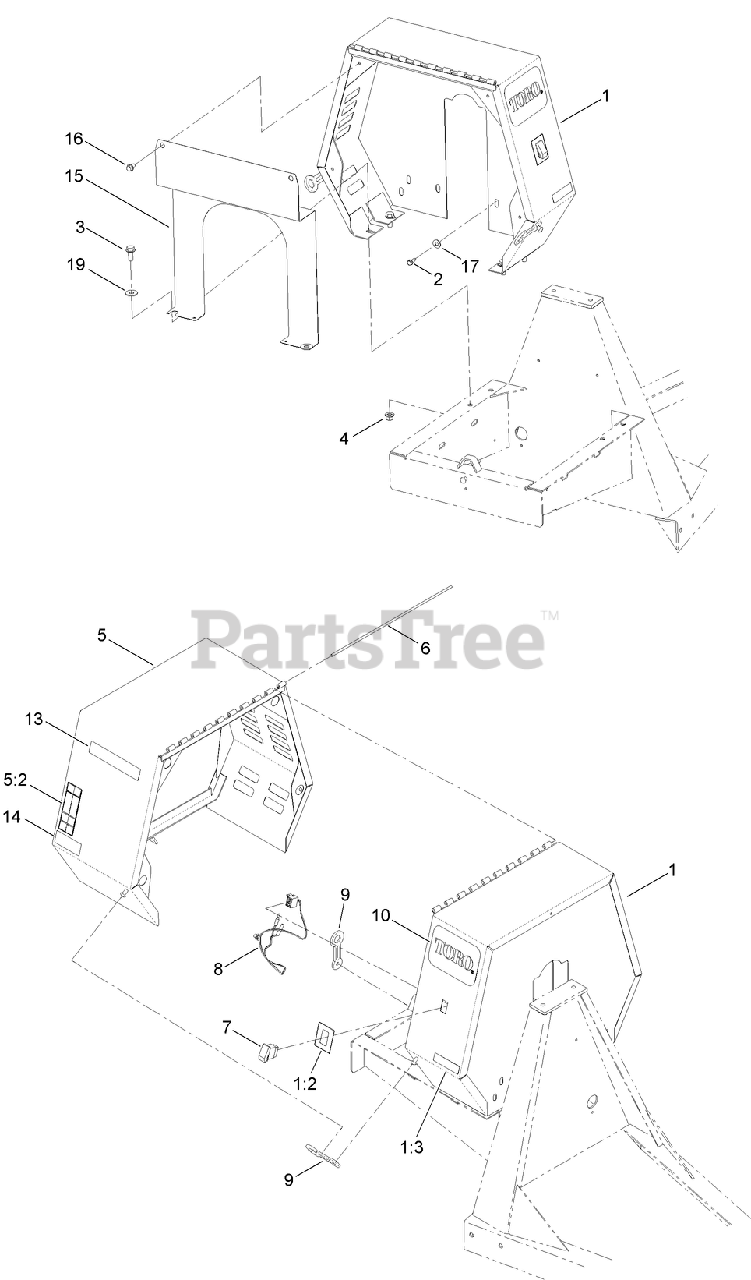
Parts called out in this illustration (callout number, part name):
1	STATIONARY COWL ASM
1:2	DECAL-STOP, ENGINE
1:3	DECAL-ARRESTER, SPARK
2	SCREW-HWHTF
3	SCREW-HHF
4	NUT-LOCK
5	MOVABLE COWL ASM
5:2	DECAL-WARNING
7	SWITCH
8	HARNESS-WIRE, MIXER
9	LATCH-RUBBER
10	DECAL
15	PLATE-ENGINE
16	SCREW-HWH
17	WASHER-FLAT
19	WASHER-FLAT
